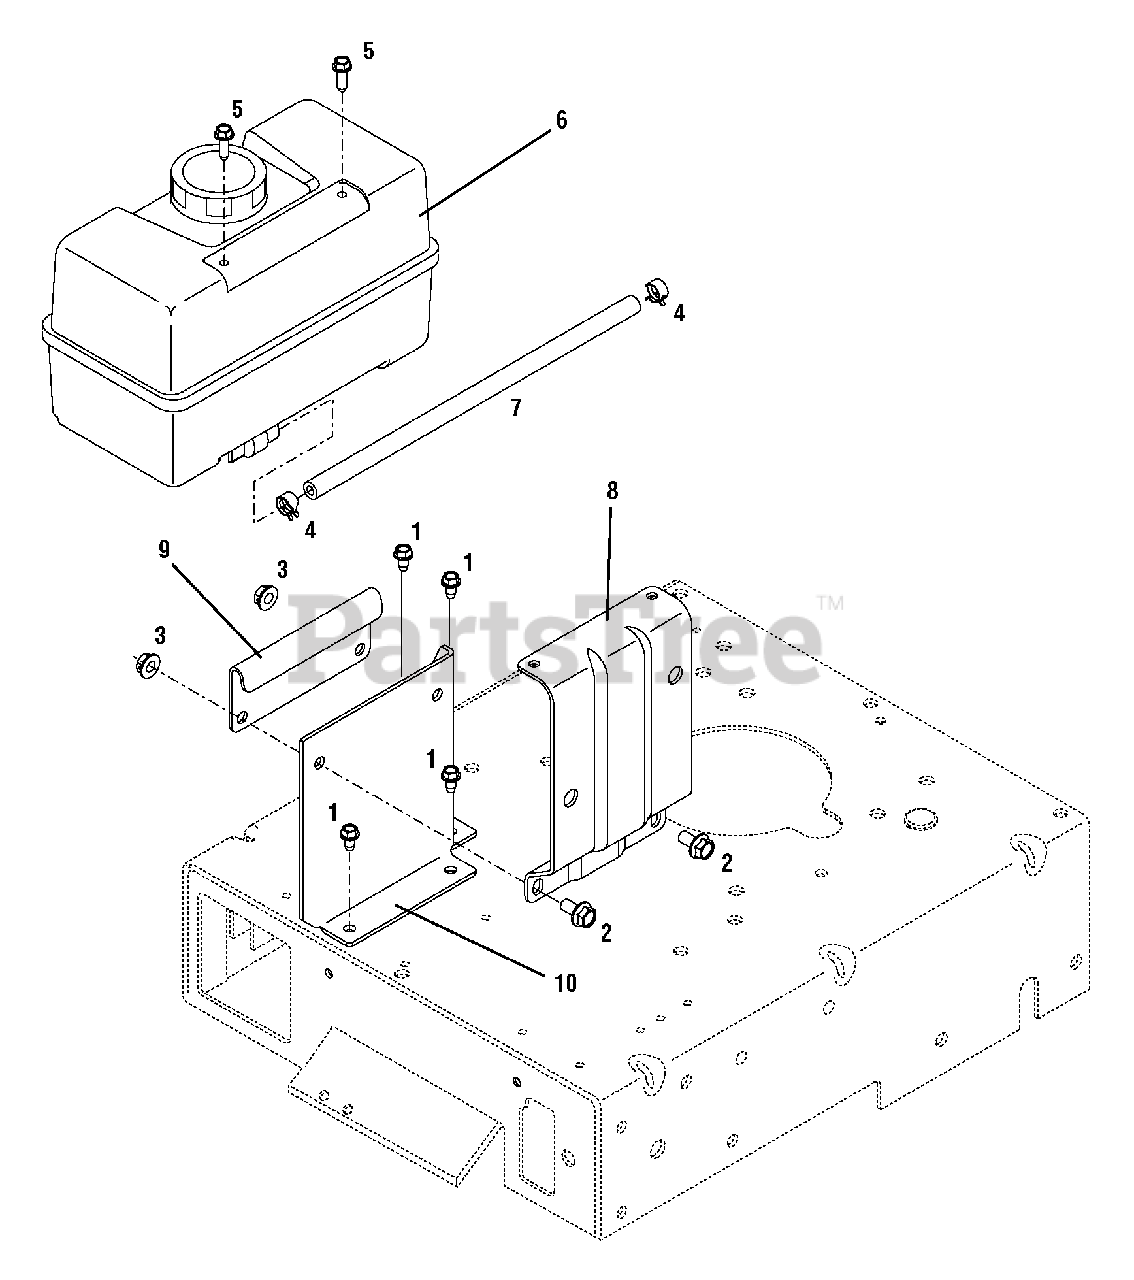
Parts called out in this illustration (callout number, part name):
1	Self-tapping Screw, 1/4-20 x 1/2
2	Hex Flange Screw, 5/16-18 x 5/8
3	Flange Locknut, 5/16-18
4	Hose Clamp
5	Screw, K80 x 3.59
6	Fuel Tank, 1 gal.
7	Fuel Line, 12"
